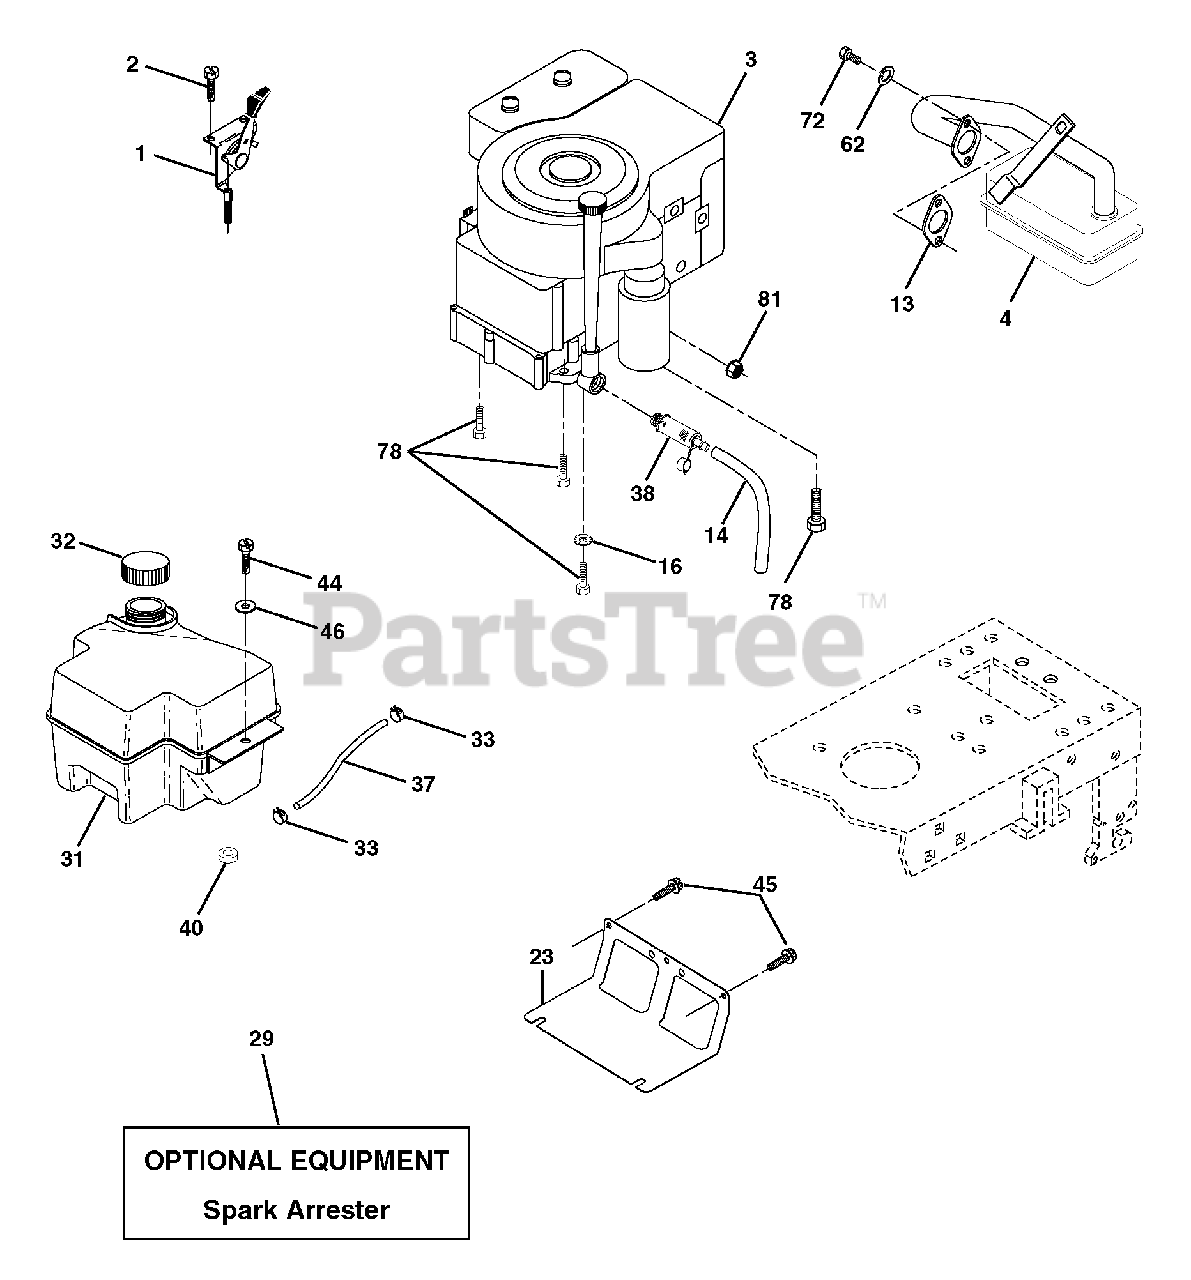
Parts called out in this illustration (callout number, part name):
1	Control Throttle/Choke
2	Screw Hex Thd Cut 1/4-20 x 1/2
13	Gasket Eng
14	Tube Drain Oil Easy
23	Shield Brn/Dbr Guard
29	Kit Spark Arrestor (Flat Scrn)
31	Tank Fuel Front
32	Cap Asm Fuel W/sym Vented
33	Clamp Hose Black
37	Line Fuel 20"
38	Plug Drain Oil Easy
40	Bushing Snap Nyl Blk Fuel Line
44	Screw Hexwsh Thdrol 1/4-20 x 3/4
45	Screw Hexwsh Thdr 3/8-16 x 3/4
46	Washer 9/32 x 7/8 x 16 Ga.
62	Washer Split
72	Screw Socket Head 5/16-18 x 1
78	Screw Hex Hd. Cap 5/16-18 x 3/4
81	Nut Keps Hex 1/4-20 unc
